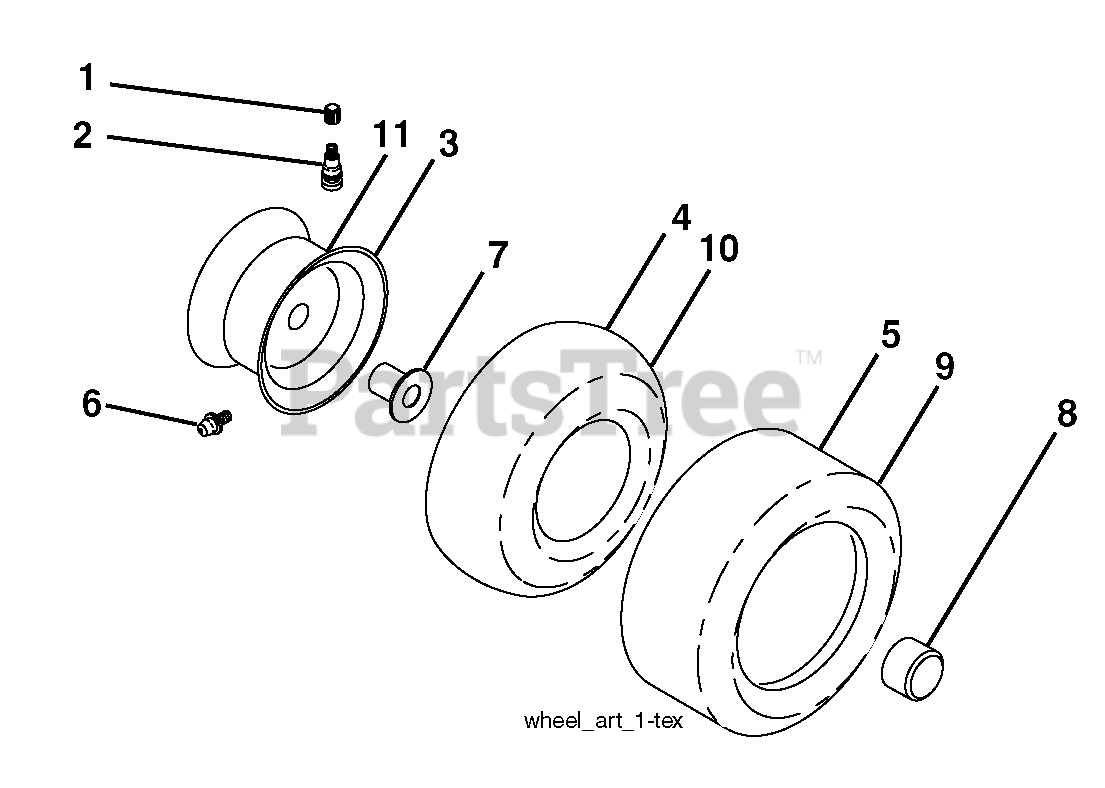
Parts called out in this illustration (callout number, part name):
1	Cap Valve Tire
2	Stem Valve
3	Rim Asm 6" Front
4	Tube Front
5	Tire Front 15 x 6.0-6
6	Fitting Grease
7	Bearing Flange
8	Cap Axle Blk 1 50 x 1 00
9	Tire Rear 18 x 9.5-8 "Turf Saver LT"
10	Tube Rear
11	Rim Asm 8" Rear
